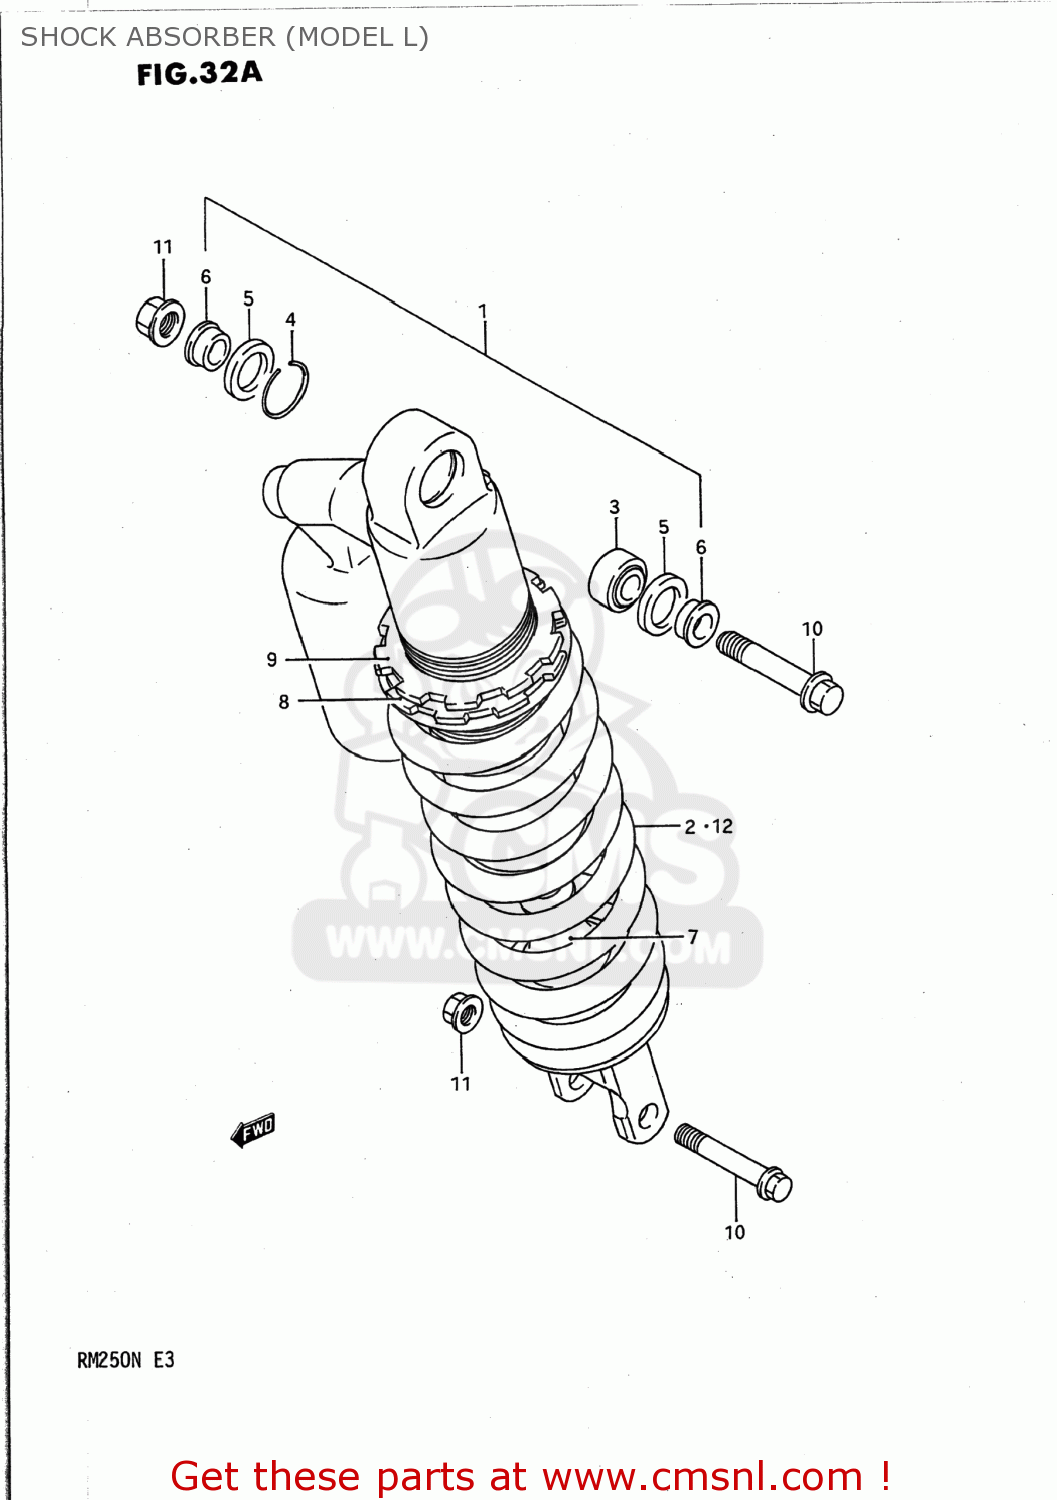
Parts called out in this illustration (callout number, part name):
1	ABSORBER ASSEMBLY,REAR SHOCK
2	SPRING
3	BEARING,RR CUSHION LEVER
4	RING
5	DUST SEAL
6	COLLAR
7	ROD,PISTON
8	GUIDE,SPRING
9	NUT
10	BOLT,REAR SHOCK ABSORBER
11	NUT
12	SPRING (HARD)
